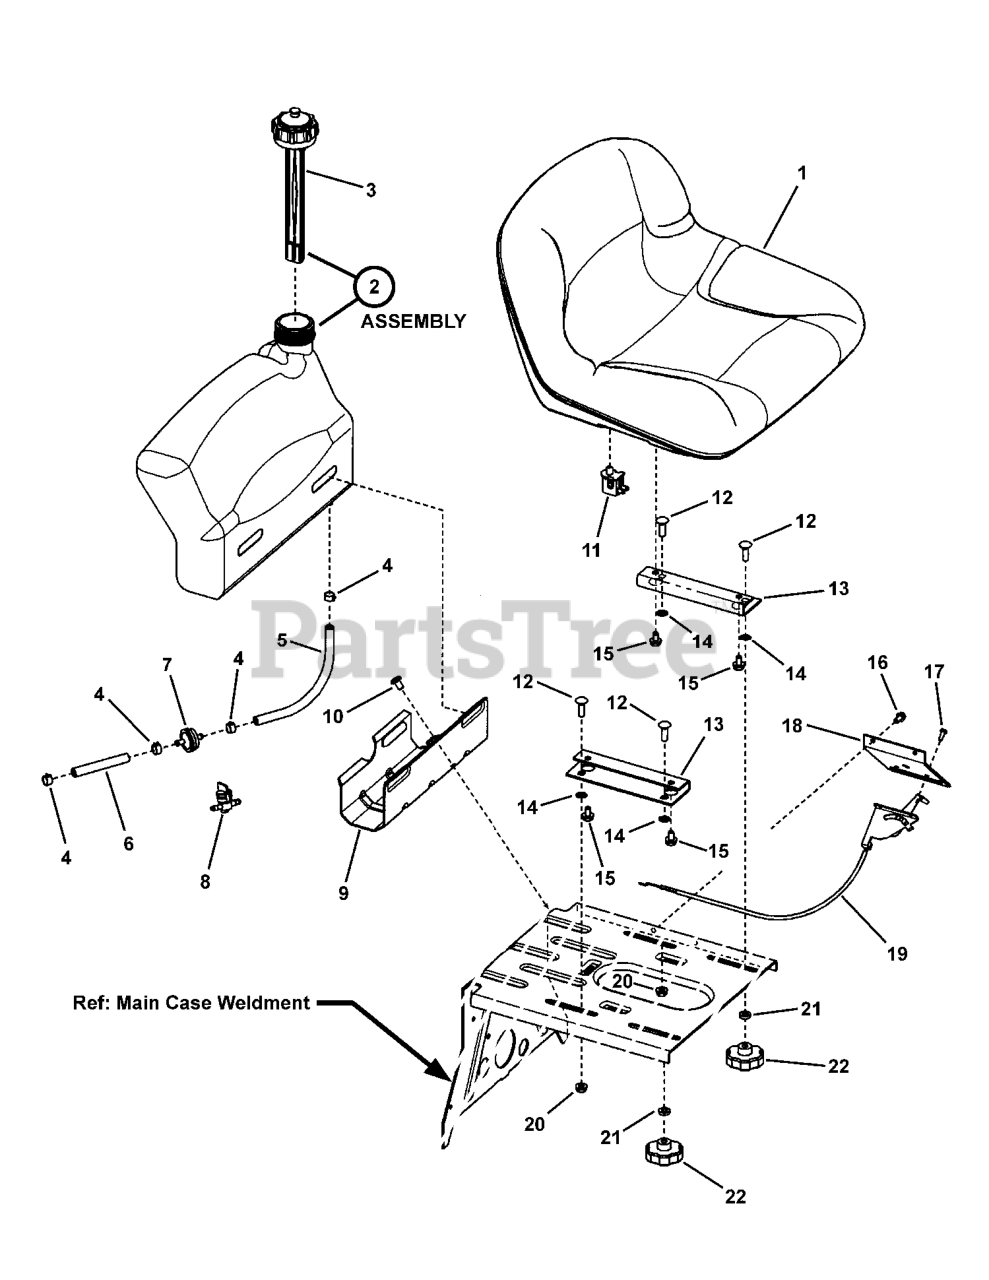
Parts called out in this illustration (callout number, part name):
2	ASSEMBLY, Fuel Tank with Gauge (Includes Cap w/Gage)
3	CAP, Fuel Tank w/Gage
4	CLAMP, Hose
5	LINE, Fuel
6	LINE, Fuel
7	FILTER, Fuel (In-Line)
8	VALVE, Fuel Shut-Off (Accessory)
9	BRACKET, Fuel Tank
10	SCREW, Phillips Head Taptite, Torx 5/16C x 1/2
11	SWITCH, Seat, Push Button (NC)
12	Bolt, Carriage,Short Neck, 5/16 X 1
13	PLATE, Seat Adapter
14	BOLT, Retainer 5/16-18
15	BOLT, 5/16-18 x 1/2 Hex Flange Nyloc
16	SCREW, 1/4-20 x 5/8" Hex Washer Head Self-Tap
17	SCREW, Hex Washer Head, Self-Tap, #10-24 x 1/2 (Torx)
18	PLATE, Throttle
19	CONTROL, Throttle (23.6" long) (Briggs Engines)
20	NUT, Hex, Centerlock
21	SPACER, .33 x .63 x .156
22	KNOB, Fluted, 5/16-18 internal thread (2.15 O.D.)
